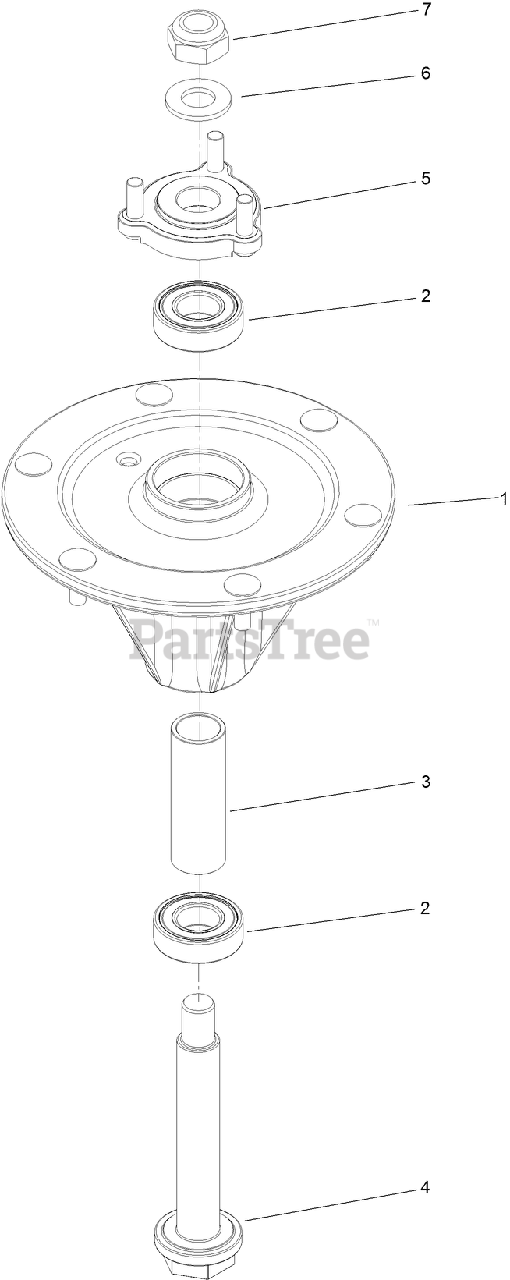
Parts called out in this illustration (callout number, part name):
1	HOUSING-SPINDLE, LH (W/STUDS)
2	BEARING-BALL
3	SPACER-BEARING
4	SHAFT-LH, SPINDLE-BALL BEARING
5	HUB-SPINDLE (W/STUDS)
6	WASHER
7	NUT-LOCK,NI LEFT HAND THREAD
